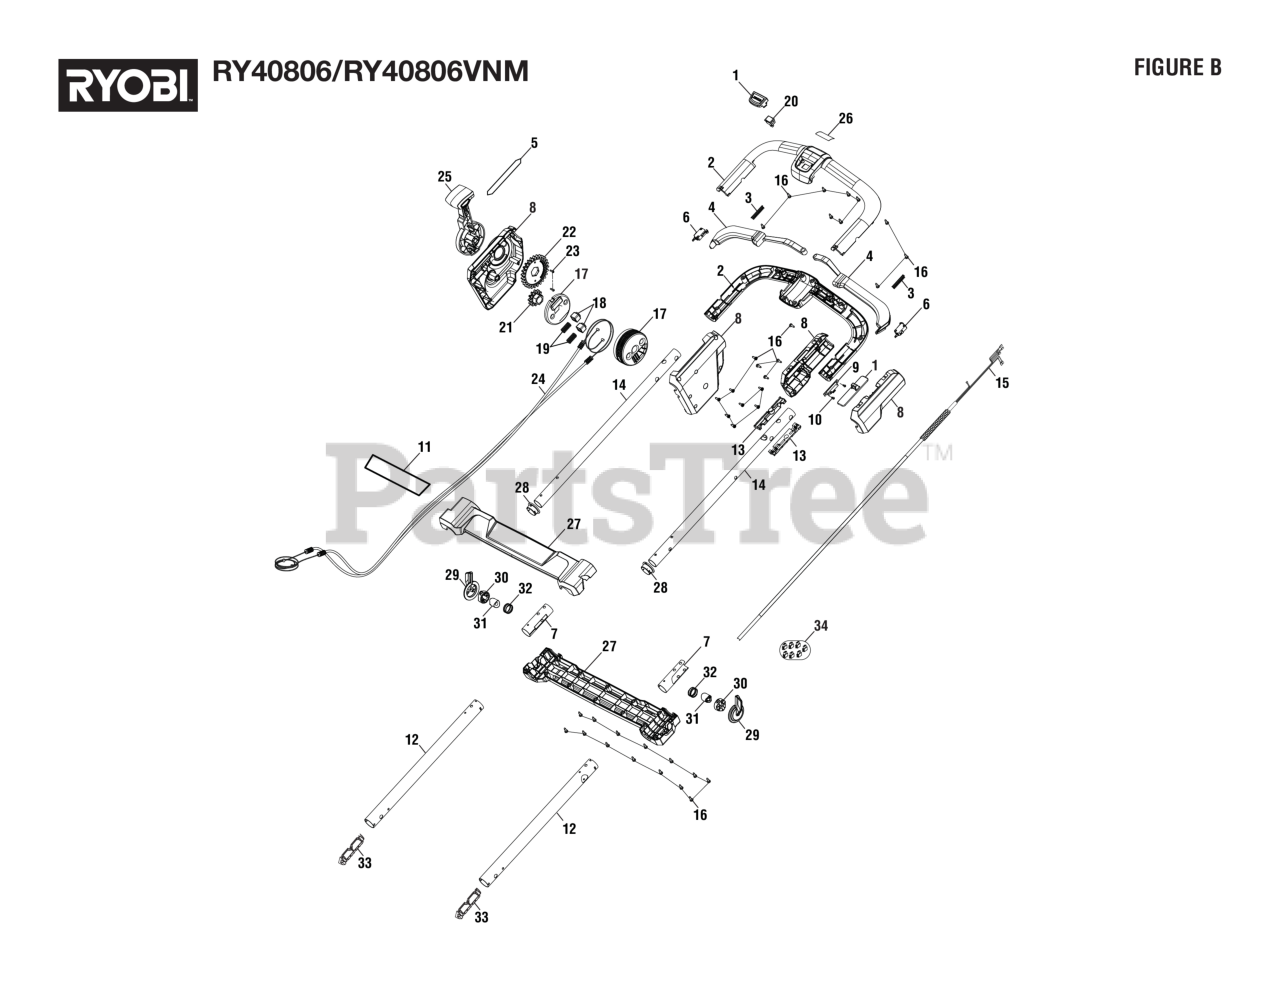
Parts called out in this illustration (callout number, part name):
1	Switch Button Assembly
2	Handle Cover Assembly
4	Trigger Assembly
5	Chute Direction Label
6	Switch (Red)
7	Handle Tube Bushing
8	Chute Adjust & Speed Control Assembly
9	Variable Switch
10	SCREW, CH M3 PH B\L=6MM
11	Logo Label (Crossbar)
12	Lower Tube
13	Upper Cable Gland
14	Upper Handle Tube
15	Wire Assembly
16	Screw (M4.2 x 12 mm, T20 Torx Pan Hd.)
17	Cable Drum Assembly
18	Cable Trainer Sleeve
20	Center Switch
21	Upper Drum Gear
22	Lever Gear
23	Screw (M3 x 22 mm, T10 Torx Pan Hd.)
24	Control Cable Assembly
25	Chute Rotation Handle
26	Starting Instructions Label
27	Cross Bar Assembly
28	Handle Tube Bushing (Small)
29	Handle Latch
30	Disc Holder
31	Compression Disc (45A)
32	Handle Compression Spring
33	Lower Cable Bushing
34	Terminal Block w/Screw
